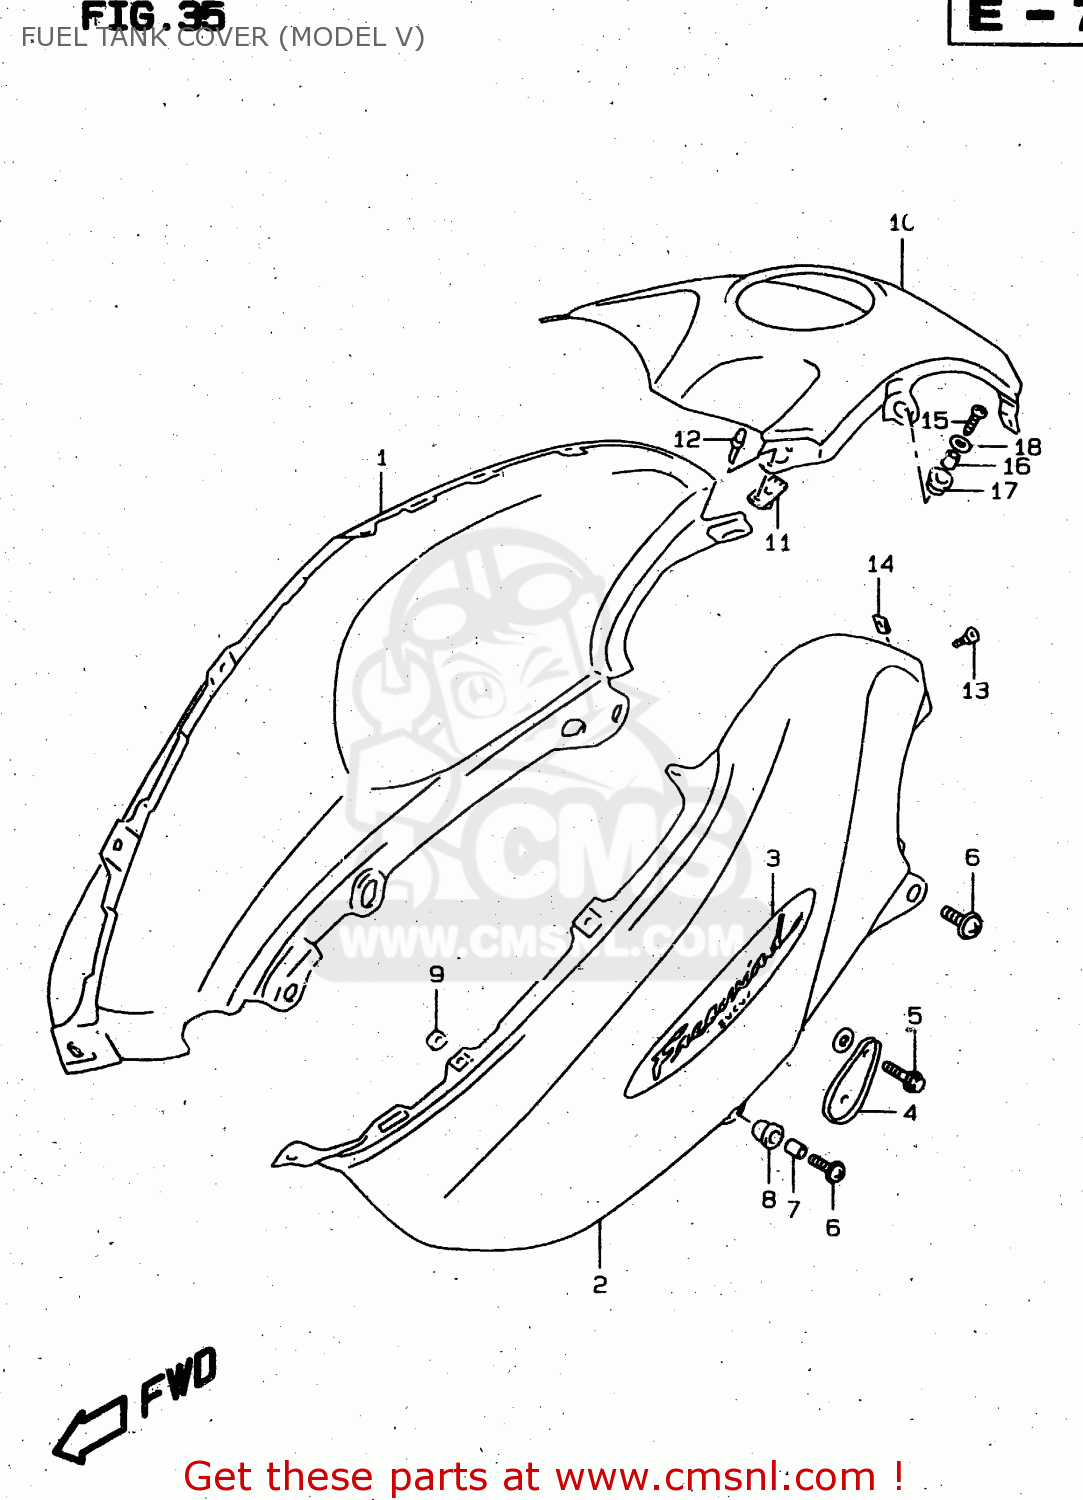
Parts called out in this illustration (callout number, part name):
1	COVER,FUEL TANK,R
2	COVER,FUEL TANK,L
3	EMBLEM, TANK
4	BRACKET,SIDE COVER,SIDE
5	BOLT
6	SCREW (6X20) WITH WASHER
7	SPACER(6.5X9X10)
8	CUSHION
9	NUT,HEADLAMP HOUSING,UPPER
10	COVER,FUEL TANK UPR
11	PLATE
12	RIVET
13	SCREW(5X16)
14	NUT,HEADLAMP HOUSING,UPPER
15	SCREW
16	SPACER(6.5X9X10)
17	CUSHION
18	WASHER(6.5X18X1)
